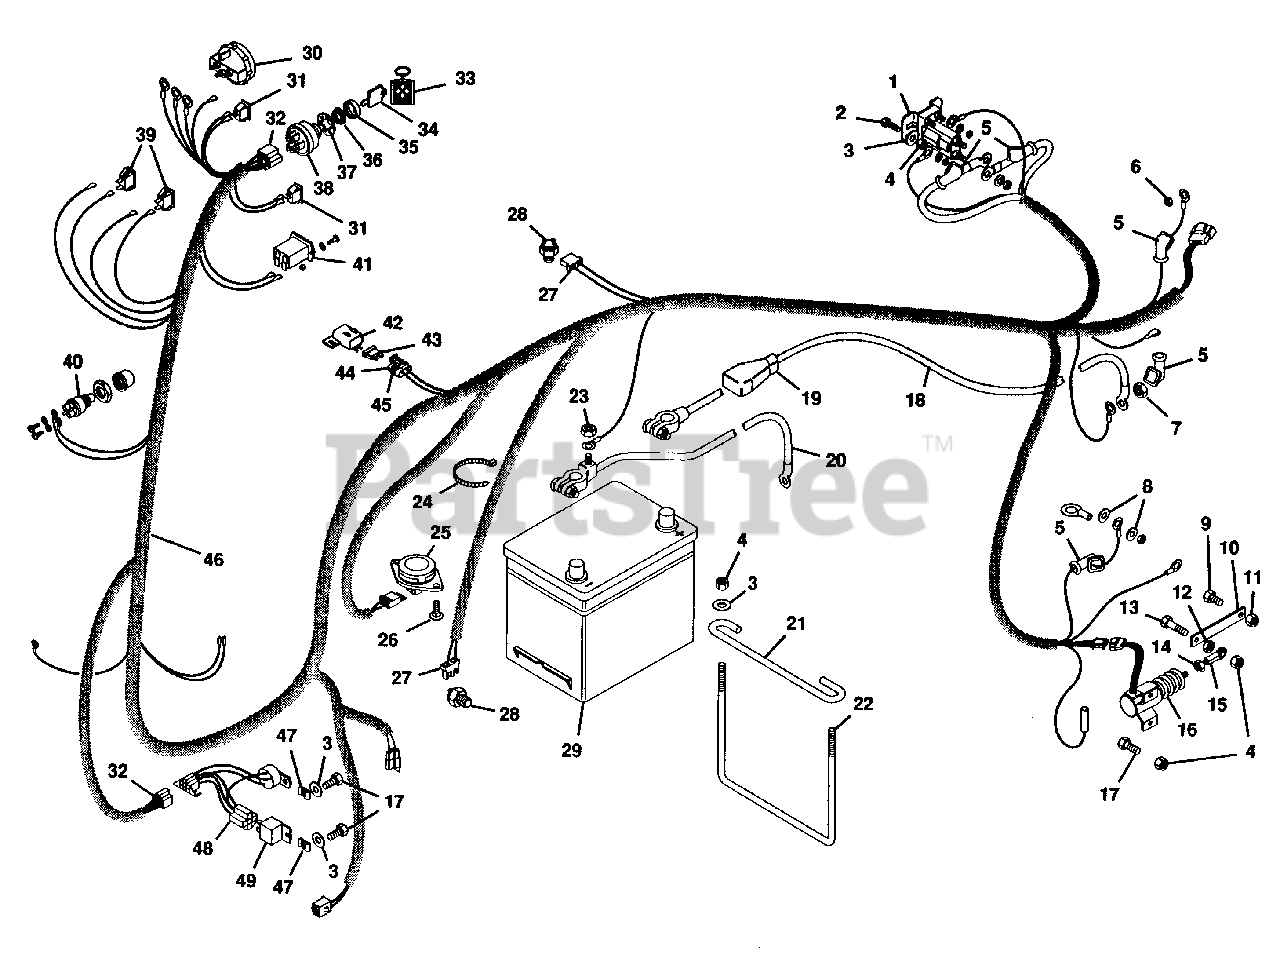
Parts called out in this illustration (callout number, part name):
1	Switch, Magnetic
2	Bolt, Hex 1/4-20x.75
3	Washer, Flat .281x.625x.065
4	Nut, Lock 1/4-20
5	Boot, Battery Cable
6	Nut, 6mm
7	Nut, Hex M8x1.25
8	Washer, Flat .188x.438x.049
9	Bolt, Hex 1/4-28x.50
10	Plate, Stop
11	Nut, Lock1/4-28
12	Nut, Hex 1/4-20
13	Bolt, Hex 1/4-20x1.25
14	Nut, Jam 1/4-28 Hex
15	Rod End, Female 1/4-28
16	Solenoid, Engine Stop
17	Bolt, Hex 1/4-20x.625
18	Cable, Positive Battery
19	Cover, Battery Terminal
20	Cable, Negative Battery
21	Rod, Battery
22	Rod, Hold Down
23	Nut, Hex 5/16-18
24	Tie Wrap, Black
25	Switch, Seat
26	Screw, Machine 1/4-20x.50
27	Connector, 2-Wire Switch
28	Switch, Interlock
29	Battery, 24-F
30	Gauge, Water Temperature
31	Switch, Blank
32	Connector
33	Chain, Key
34	Key, Ignition Switch
35	Boot, for 9/16 Switch Nut
36	Nut, 9/16-24 for Switch
37	Washer, Lock
38	Switch, Ignition
39	Light, Indicator
40	Switch, Preheater
41	Hourmeter
42	Cover
43	Fuse, 25 Amp
44	Terminal, 14-16 Gauge
45	Connector
46	Harness, Wiring
47	Nut, Speed 1/4-20
48	Module, Time Delay
49	Relay
